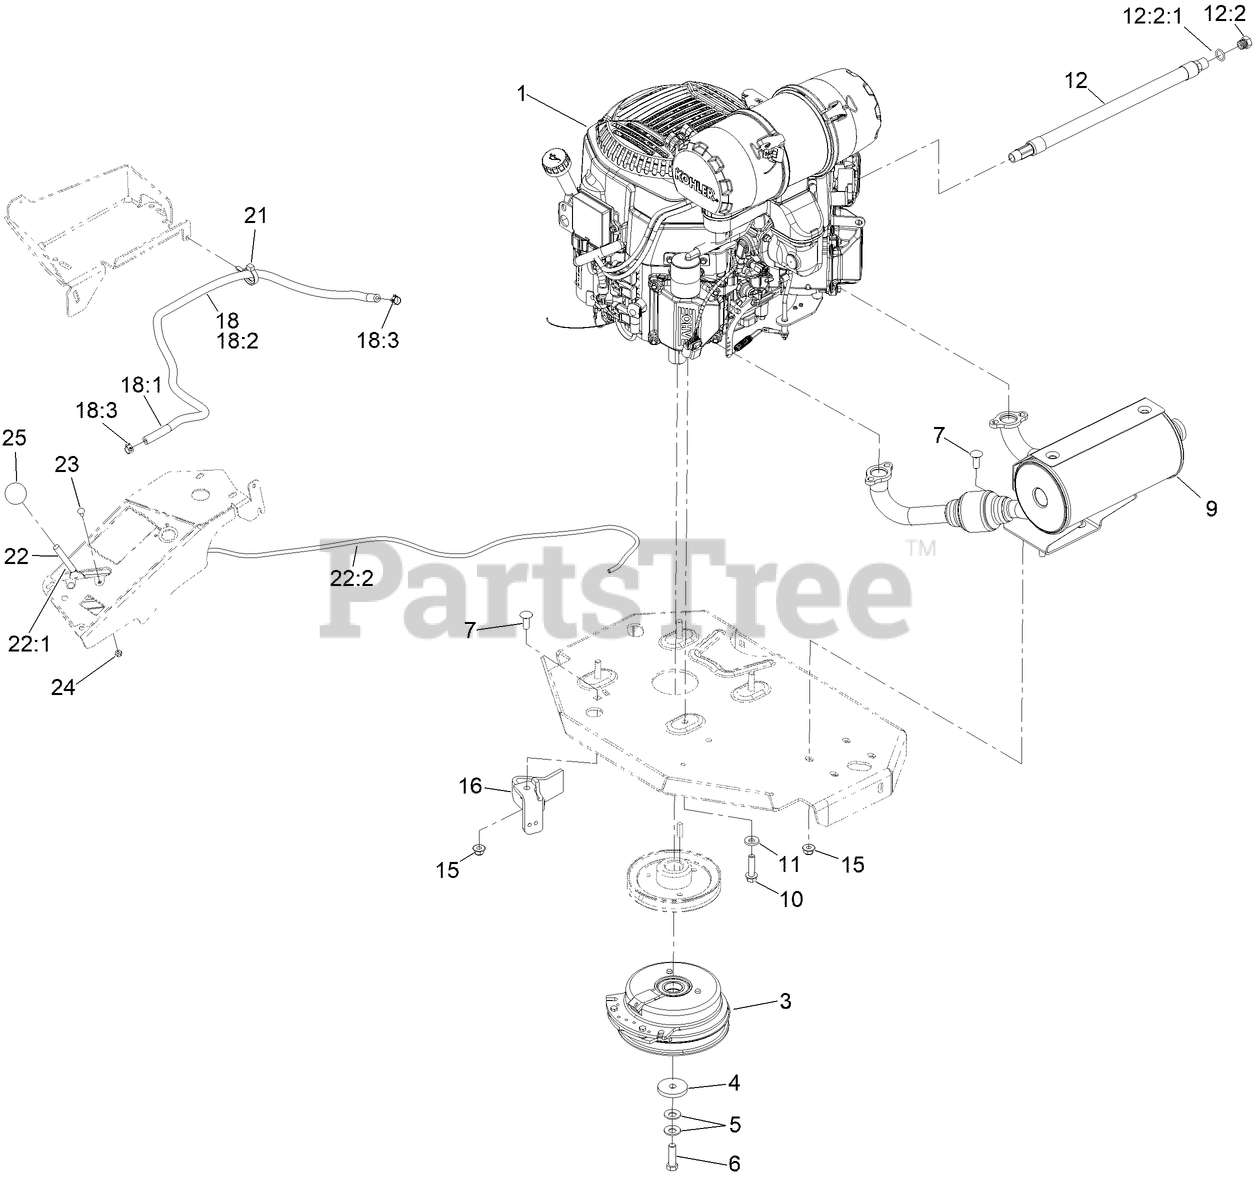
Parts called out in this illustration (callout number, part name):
1	ENGINE-KOHLER
3	CLUTCH KIT
4	WASHER-CLUTCH
5	WASHER-SPRING
6	SCREW-HH, W/LOCTITE
7	SCREW-CARR
9	KIT,MUFFLER
10	SCREW-HWH
11	WASHER-BELLEVILLE
12	OIL DRAIN HOSE ASM
12:2	PLUG-HH
12:2:1	O-RING
15	NUT-HF, NI
16	CLUTCH-ANCHOR
18	FUEL LINE ASM
18:1	HOSE-FUEL
18:2	SLEEVE-THERMAL
18:3	CLAMP-HOSE
21	CLAMP-HOSE
22	THROTTLE CONTROL ASM
22:1	LEVER-THROTTLE
23	BOLT-CARR
24	NUT-LOCK, NI
25	KNOB-BALL
